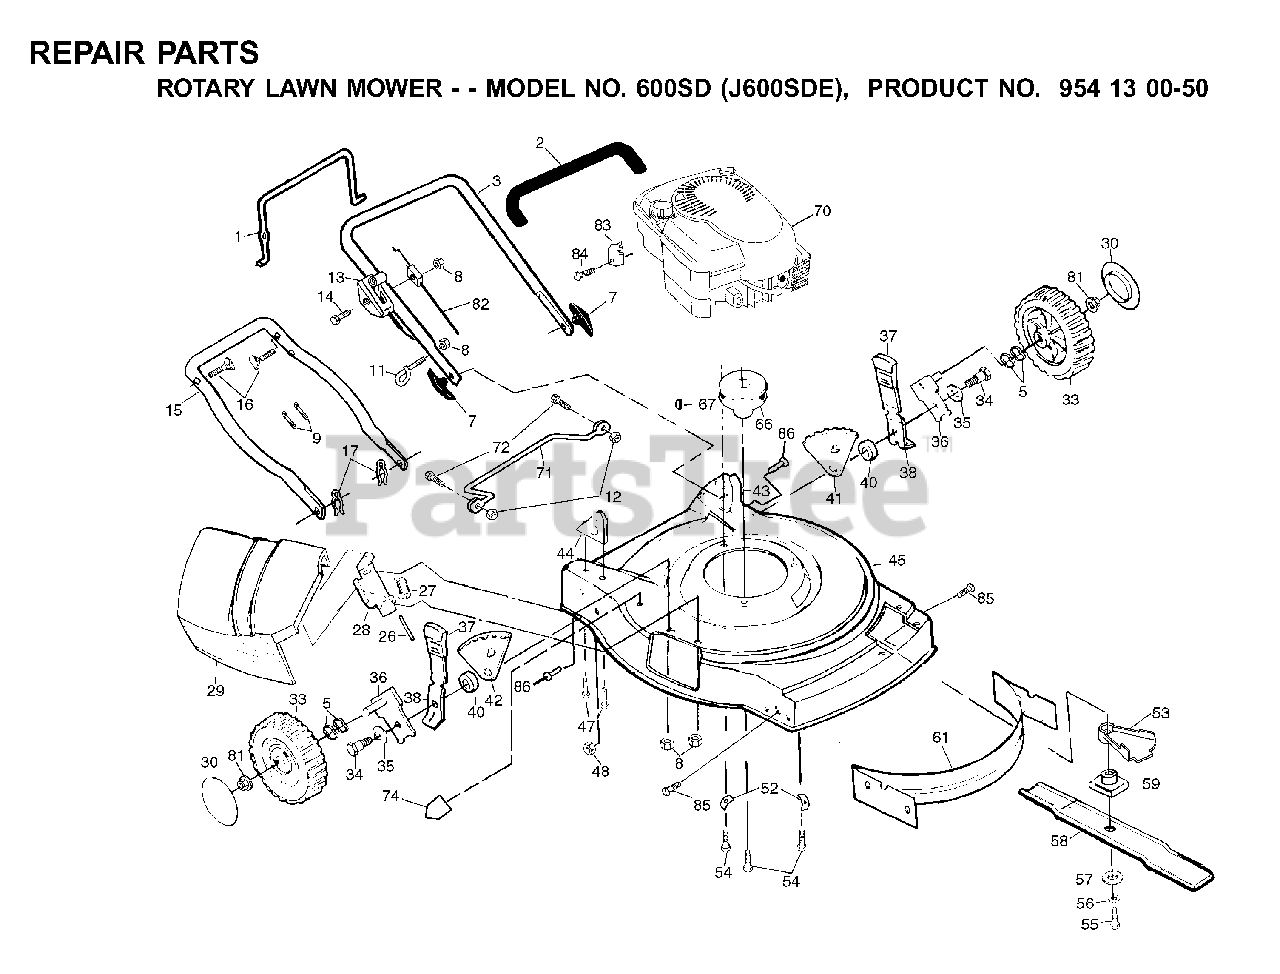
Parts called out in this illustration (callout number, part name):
1	CONTROL BAR ORANGE
2	GRIP.HANDLE.FOAM
5	WAVE WASHER
7	HANDLE KNOB
8	NUT
9	TIE GUIDE
13	THROTTLE CONTROL
14	SCREW 1/4-20 X 2.12
15	LOWER HANDLE
16	HANDLE BOLT
17	HAIRPIN COTTER
26	ROD.HINGE.COMBI-C
27	SPRING PM
28	BRACKET PM
33	WHEEL.8X2.PR.LP.RAD.GREY
34	BOLT
35	BELLEVILLE WASHER
36	AXLE ARM
37	SELECTOR KNOB
40	RP SPACER HT ADJ
43	HANDLE BRACKET ASM. LH
44	HANDLE BRACKET ASM. RH
47	SCREW 5/16-18
48	LOCKNUT PM
53	DEBRIS SHIELD
54	BOLT 3/8-16X1-1/8
55	SCREW, HEX HD 3/8-24 X 1-3/8
56	LOCKWASHER
57	WASHER,HARDEN
58	22" BLADE (FOR MODEL 56 SFEB)
59	RP BLADE ADAPTOR
66	ENGINE.PULLEY.FWG
67	HI PRO KEY PM
74	DECAL MOWER CUT/FINGER
81	HEX FLANGE LOCKNT
82	ENGINE ZONE CONTROL
83	CABLE CLAMP(ENGINE)
84	SCREW.HEX.HEAD.WASHER.10-16
86	RIVET BLIND
